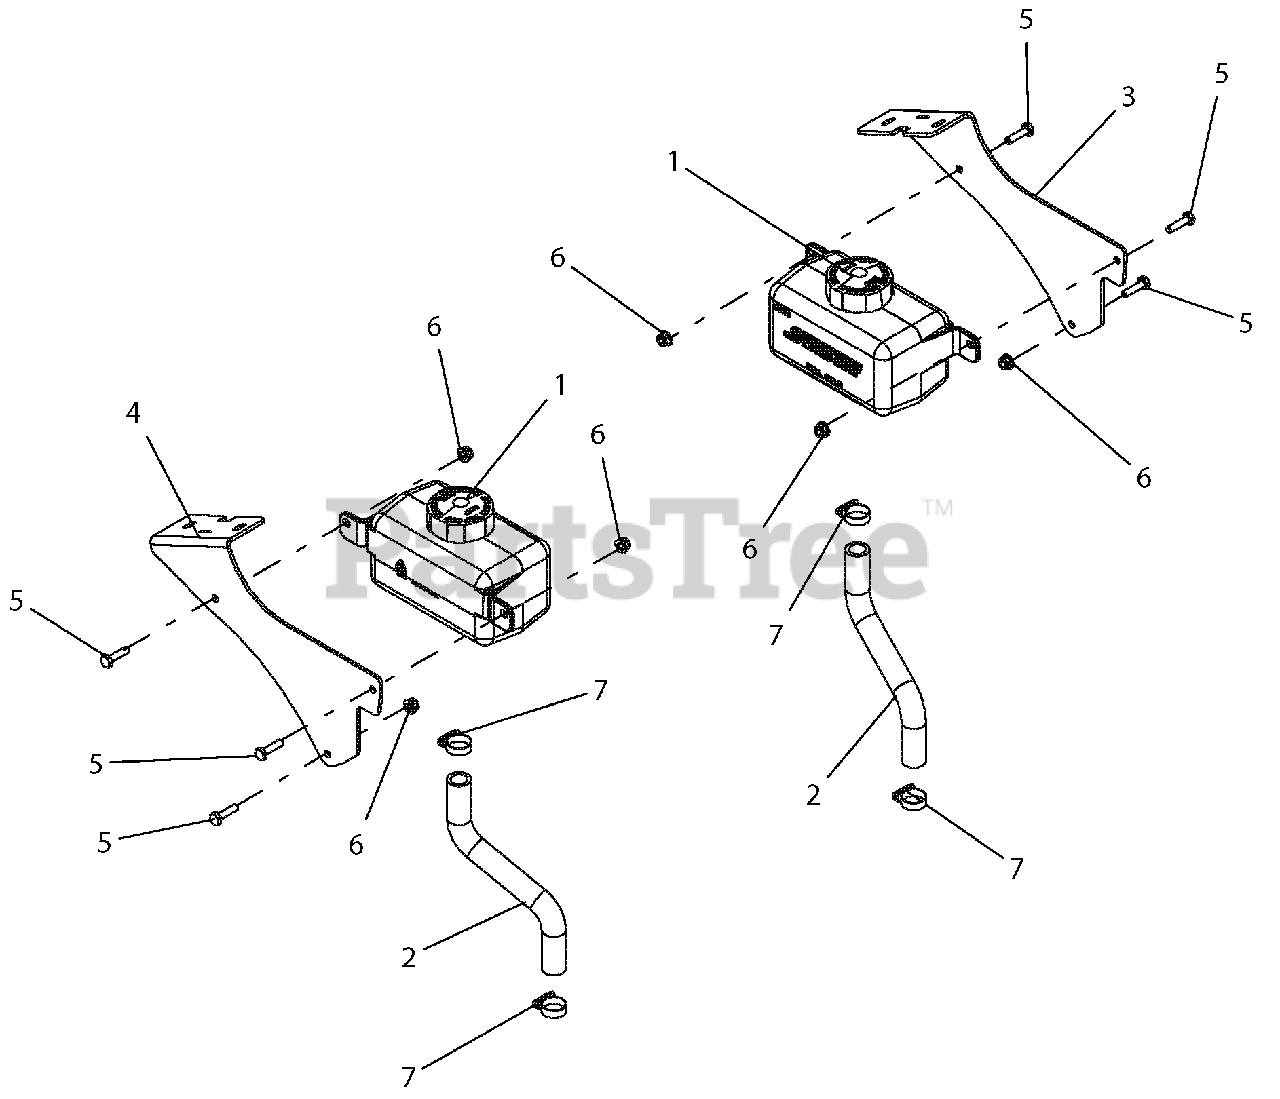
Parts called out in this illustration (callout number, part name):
1	TANK, HYD 1000ML
2	HOSE, HYDRO OVERFLOW
3	LH HYDRO OVERFLOW TANK CARB CANISTER MTG
4	BRKT, MOUNT RH HYDRO OVERFLOW TANK CARB CANISTER MTG
5	BLT-HEX .25-20X1.00 GR5 YWZC
6	NUT-LK-NYL-FLG .25-20 YWZC
7	CLAMP, .88 DIA HOSE
